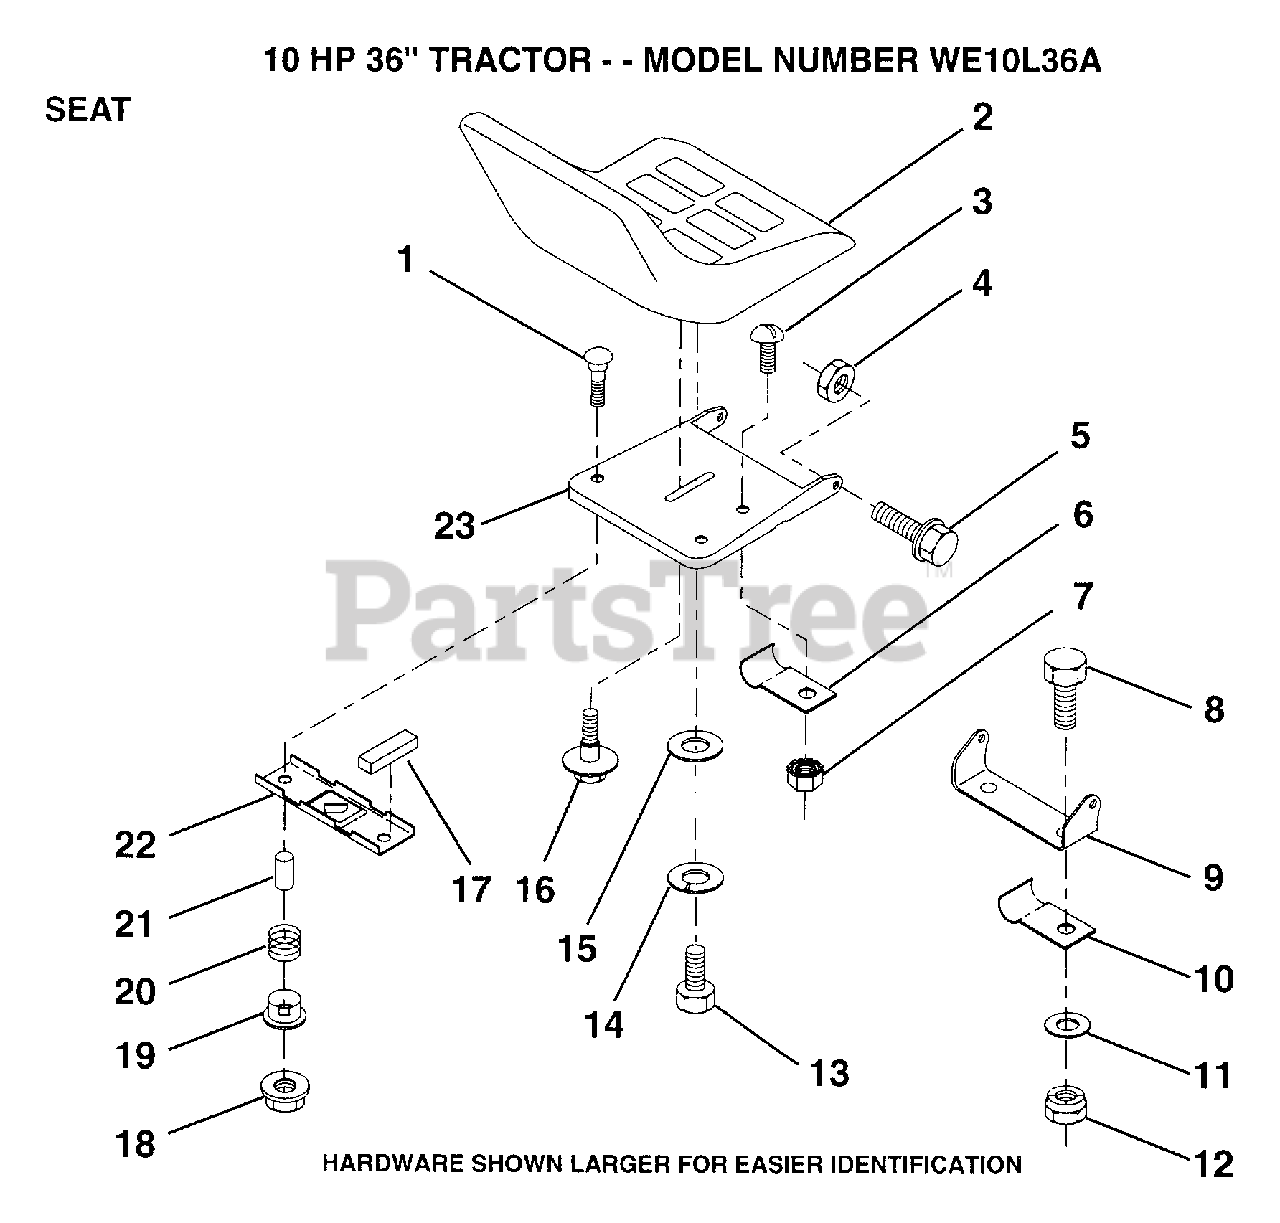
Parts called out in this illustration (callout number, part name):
7	"NUT,KEPS"
10	"CLIP,INSULATOR"
11	WASHER
13	BOLT
14	LOCKWASHER
15	WASHER
16	"BOLT,SHOULDER"
17	STRIP FORM
19	BUSHING
20	SPRING
21	SPLIT SPACER
22	BRKT SWITCH
